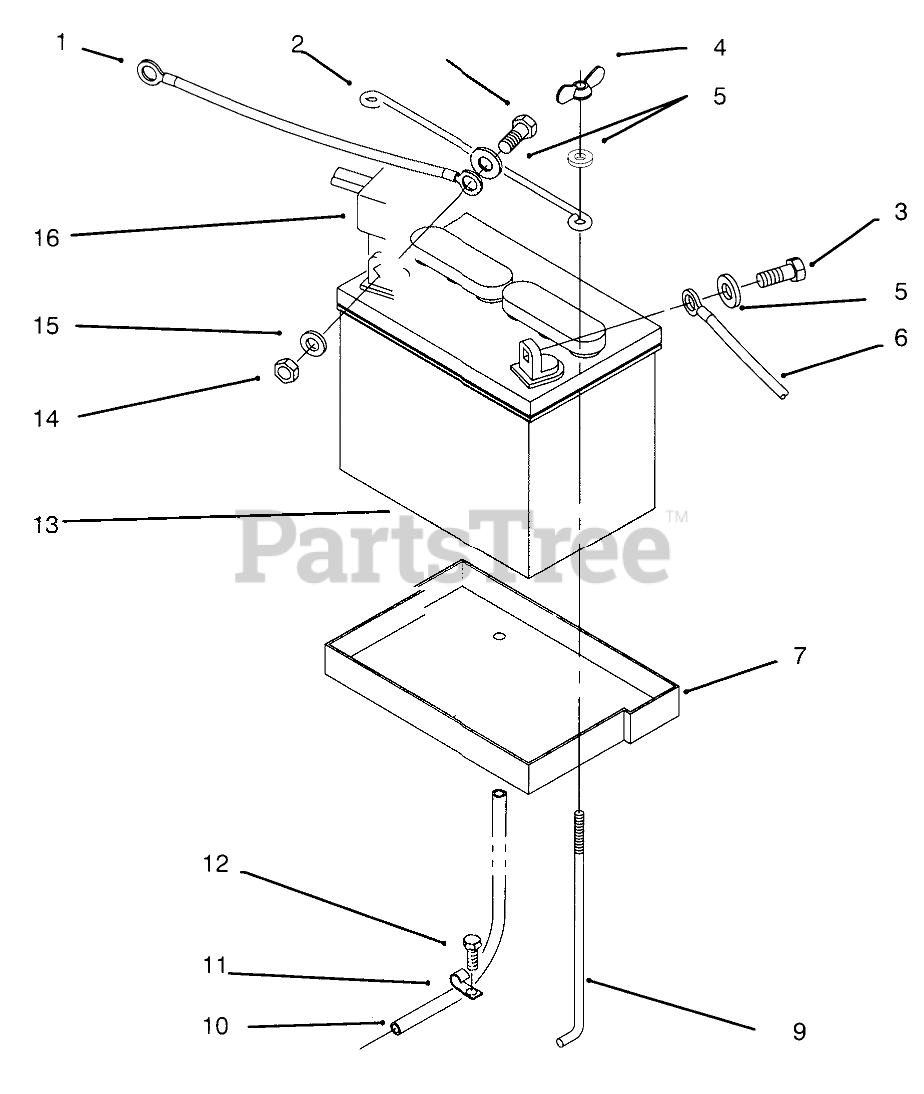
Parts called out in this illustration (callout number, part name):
1	ASSY WIRE
2	HOLDDOWN-BATTERY
3	SCREW-HH
4	NUT-WING
5	WASHER-FLAT
6	ASSY WIRE
7	TRAY-BATTERY
9	HOOK-BATTERY RETAIN
10	TUBE-21" BATTERY DRAIN
11	CLIP
12	SCREW-HH
13	Battery
14	Nut
15	WASHER-LOCK
16	Boot
